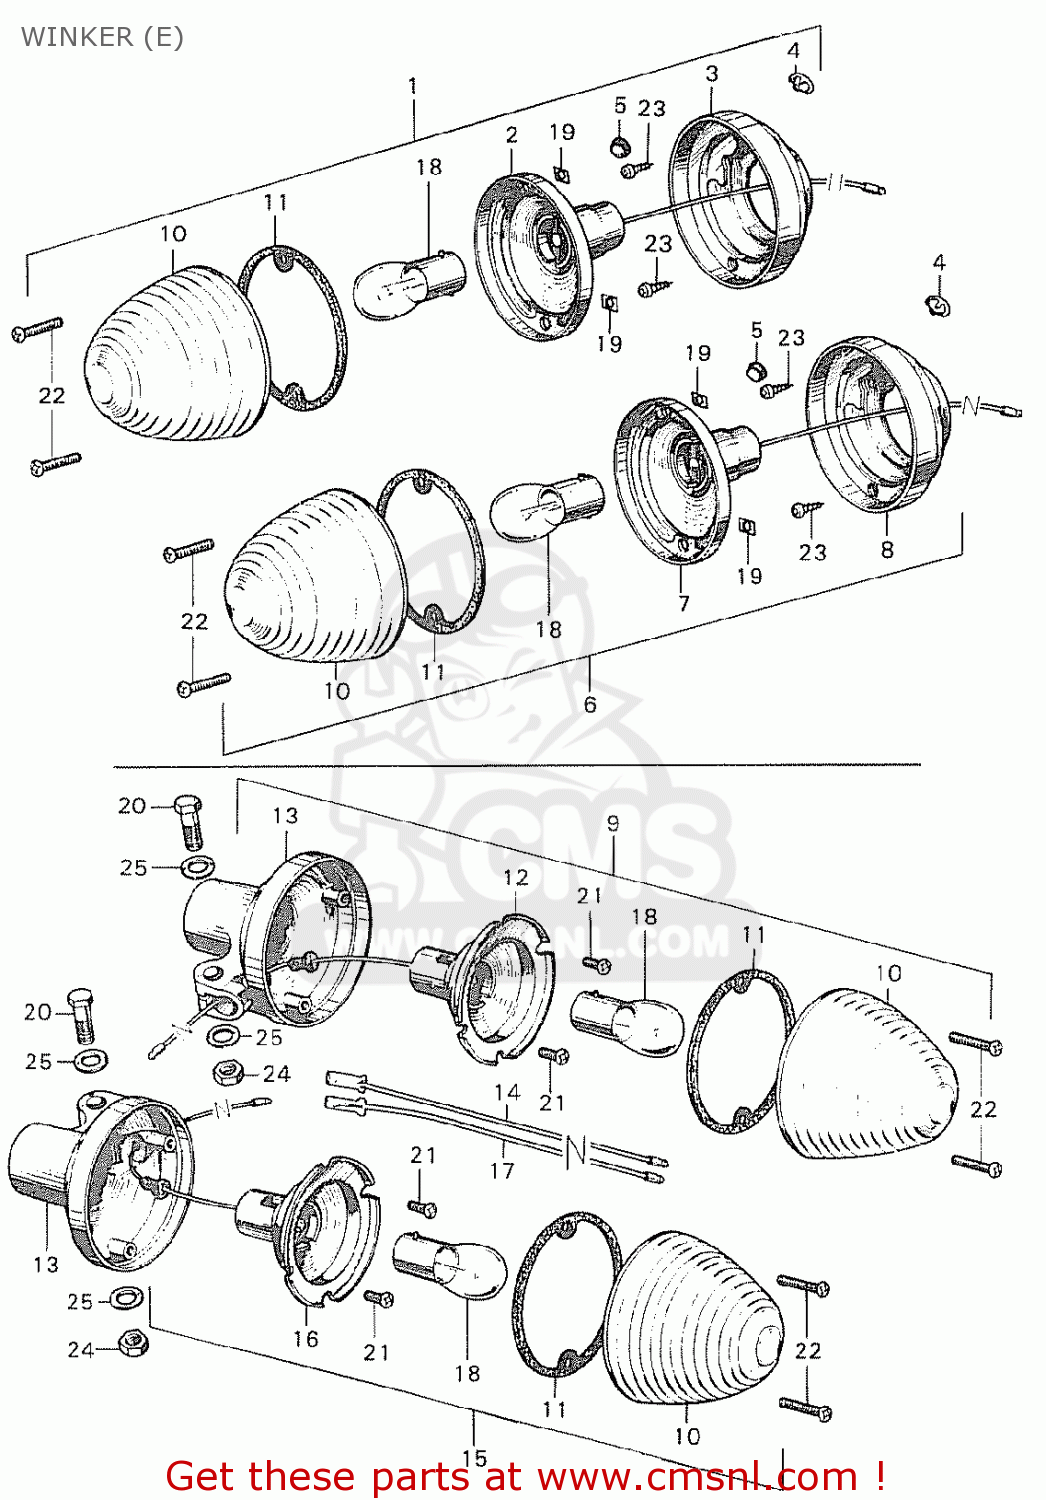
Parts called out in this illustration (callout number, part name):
1	ASSY,R FR WINKER
2	SOCKET, R.RR WINKER
3	BASE,R.FR.WINKER
4	LENS WINKER PILOT
5	LENS, WINKER PILOT
6	ASSY,L,FR WINKER
7	SOCKET,L.FRWINKER
8	BASE L.FR.WINKER
9	ASSY R RR WINKER
10	LENS, WINKER
11	PACKING,WINKER
12	SOCKET R RRWINKER
13	BASE RR.WINKER
14	SUBCORD RR WINKER
15	ASSY L RR WINKER
16	SOCKET,L.WINKER
17	SUBCORD WINKER
18	BULB,WINKER
19	NUT, SPECIAL
20	BOLT,HEX 6X28
21	SCREW CROSS 3X5
22	SCREW CROSS 3X12
23	SCREW,4X8
24	NUT,HEX 6MM
25	WASHER,PLAIN, 6MM
